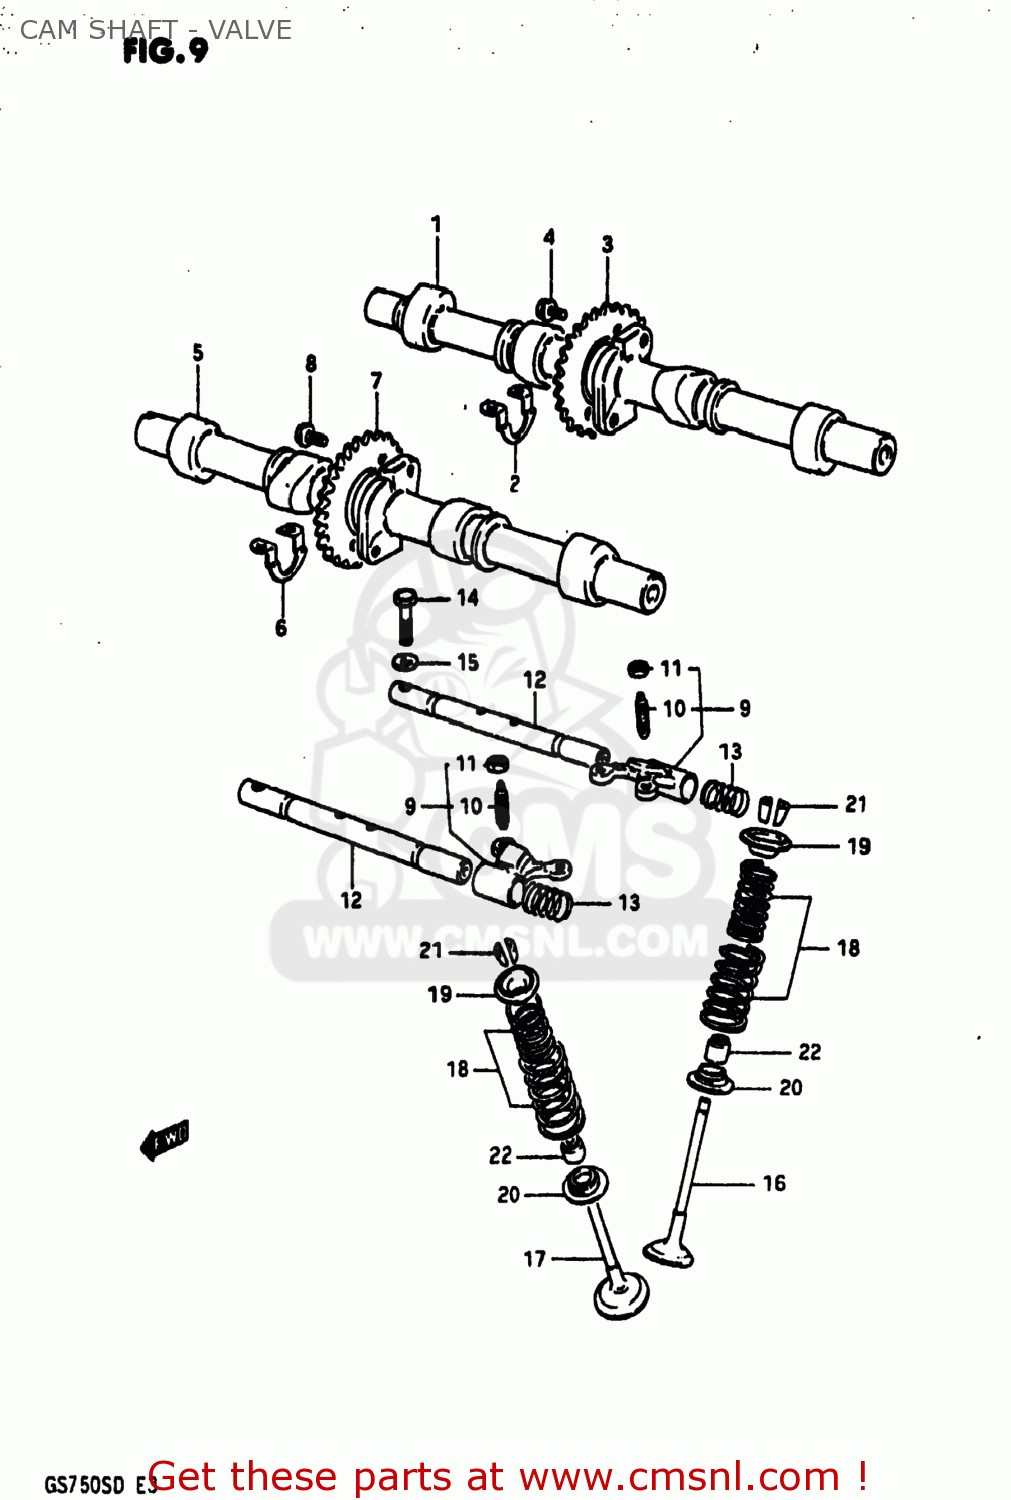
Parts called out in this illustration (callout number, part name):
1	CAMSHAFT SET,INTAKE
2	SHIM,CAMSHAFT
3	SPROCKET,INTAKE CAMSHAFT
4	BOLT(7X11)
5	CAMSHAFT SET,EXHAUST
6	SHIM,CAMSHAFT
7	SPROCKET,EXHAUST CAMSHAFT
8	BOLT(7X11)
9	ARM,VALVE ROCKER
10	SCREW,TAPPET ADJUSTING
11	NUT,ADJUSTING
12	SHAFT,VALVE ROCKER
13	SPRING
14	BOLT
15	WASHER
16	VALVE,INTAKE
17	VALVE,EXHAUST
18	SPRING SET,VALVE
19	RETAINER,VALVE SPRING
20	SEAT,VALVE SPRING
21	COTTER VALVE
22	OIL SEAL
